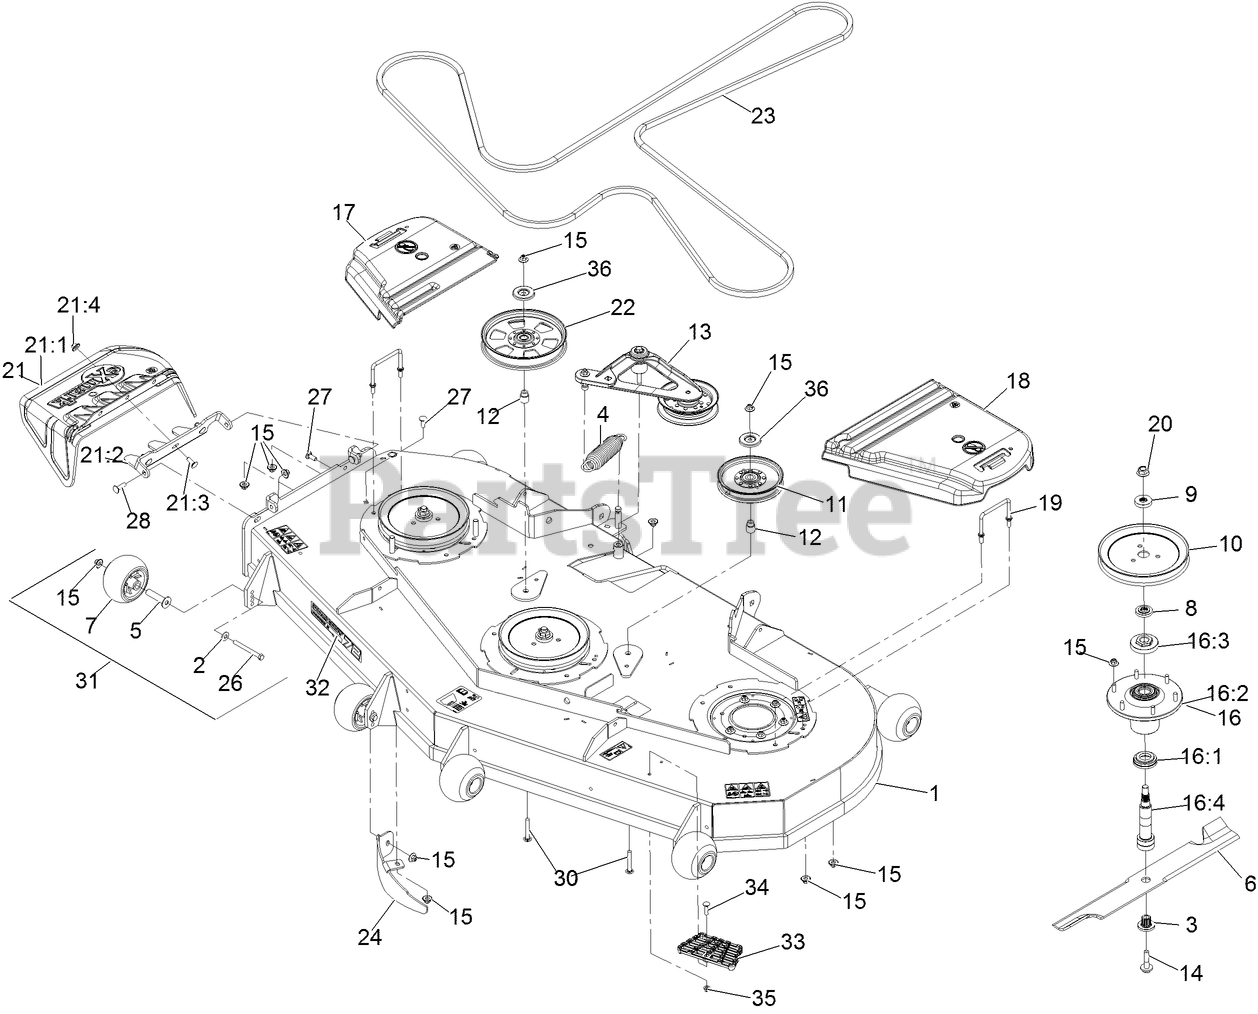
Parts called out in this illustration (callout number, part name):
1	ASM,DECK W/DECALS 724
2	WASHER-BELLEVILLE
3	BUSHING,SPLINED
4	SPRING-EXTENSION
5	AXLE, ROLLER
7	ROLLER-SCALP, ANTI
8	SPACER,SPLINED STEPPED
9	SPACER,SPLINED
10	SHEAVE,BLADE DRIVE 9.00
11	IDLER-PULLEY
12	BUSHING-IDLER
13	DECK IDLER ASM
14	SCREW,SEMS 1/2-20 X 2.19
15	Nut-Nyloc 3/8-16 Flg
16	ASM,SPINDLE HOUSING
16:1	GUARD,BOTTOM
16:2	ASM,CUTTER HOUSING
16:3	NUT, SPINDLE 7/8-14
16:4	SPINDLE,DOUBLE SPLINE
17	COVER-BELT, RH
18	COVER-BELT, LH
19	WIREFORM-COVER
20	NUT-FLANGE, CENTERLOCK
21	ASM,DISCHARGE CHUTE
21:1	CHUTE,DISCHARGE
21:2	BRACKET,DISCHARGE CHUTE
21:3	SCREW-CARR
21:4	Nut-Nyloc 3/8-16 Flg
22	PULLEY-IDLER, FLAT
23	BELT-V
24	BAFFLE-DOGLEG, LZ72
26	SCREW-HH 3/8-16 X 3 3/4 GR 8
27	SCREW-CARR
28	Bolt-Carriage 3/8-16 X 1 1/4
30	SCREW-CARR
31	KIT, ANTI-SCALP ROLLER
32	DECAL, 726
33	STEP-DECK
34	Bolt-Carriage 5/16-18 X 1 1/4
35	NUT-HF, NI
36	SHIELD-DUST
